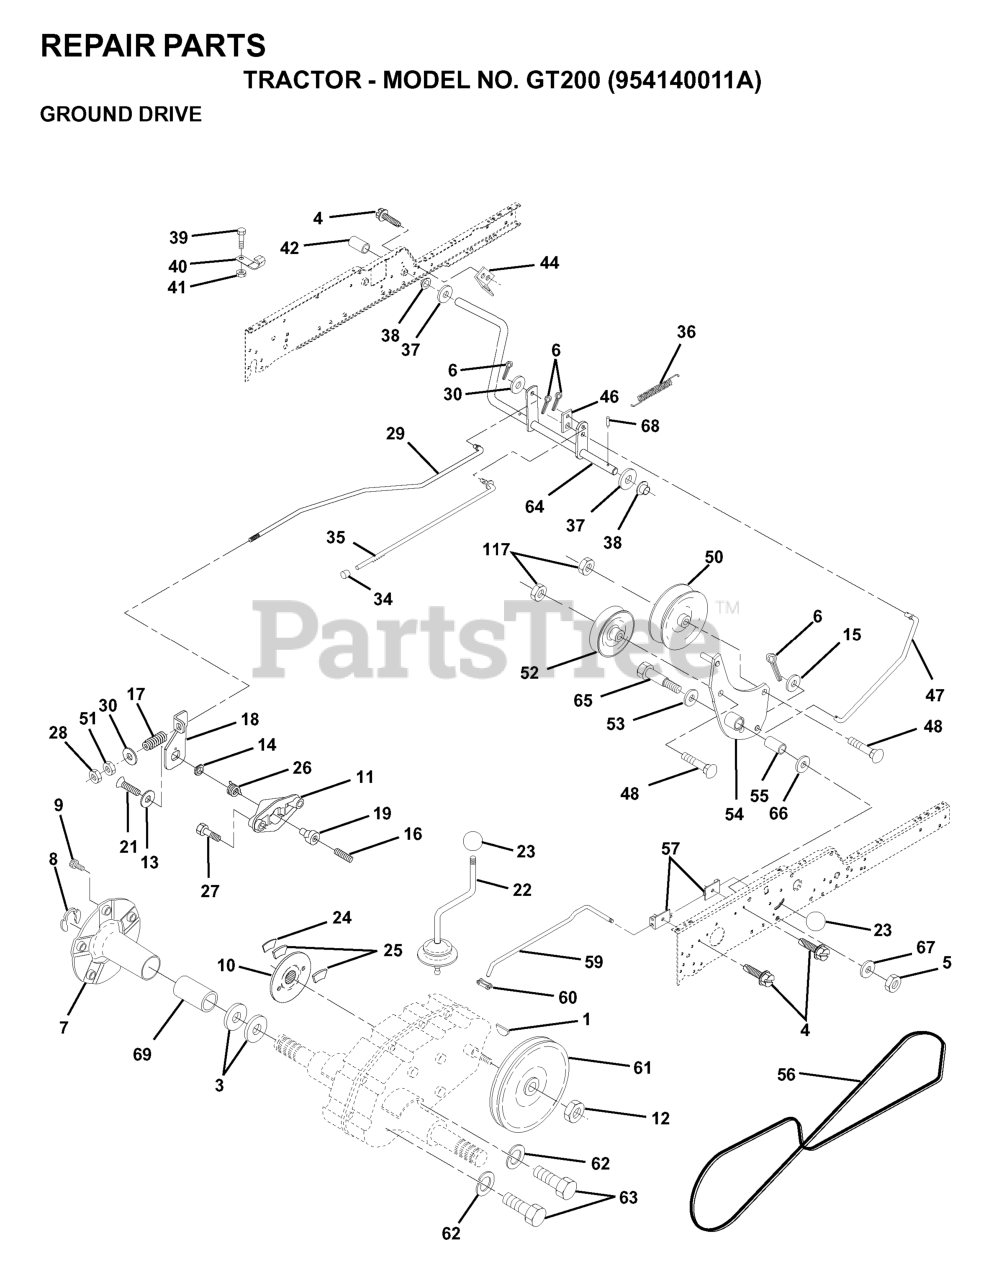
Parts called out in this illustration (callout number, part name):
1	KEY
4	Screw 5/16-18 x 1/2 Hex, Self Tapping 5/16-18 x 1/2
6	COTTER PIN
7	HUB.WHL.ASM.REAR
8	Ring, Klip Truarc #5304-75
10	DISC BRAKE
11	YOKE-BRAKE DISC
15	WASHER
17	SPRING,ROD BRAKE
18	BRAKE LEVER
19	BRAKE DISC CAM
21	Screw, Flat Head 1/4-28 x 3/4
22	GEAR SHFT LVR T
24	BRAKE PUCK SUPPORT
25	BRAKE PUCK TOP
26	RETURN SPRING
28	NUT
29	ROD BRAKE ZINC GT
30	WASHER
34	PLUNGER CAP
35	PARKING BRAKE ROD
36	SPRING DRIVE GROUND
39	Screw, Fin. #10-24 x 1
40	ACT-SWITCH T
41	LOCKNUT
42	COVER, PEDAL (1 2)
43	BOLT.HEX.1/4.X.3/4.DICHROMATE
44	BRKT SWITCH GT
45	LOCKNUT.NYLOC.1/4-20
46	RETAINER SPRING
47	CLUTCH ROD
49	Washer 13/32 x 7/8 x 13 Gauge
50	FLAT IDLER PULLEY
51	NUT
52	PULLEY.IDLER.V.
54	CLUTCH ARM ASSY
55	BEARING LT (2 2)
56	V-BELT GROUND DRIVE
57	BRACKET SHIFT ROD
59	ROD SHIFT HI LO
60	CONNECTING LINK
61	TRANSAXLE PULLEY
62	LOCKWASHER
63	BOLT
64	SHAFT CLUTCH/BRAKE PEDAL
66	WASHER.BLADE
67	WASHER
68	ROLL PIN STD
69	COVER.HUB.BLACK
